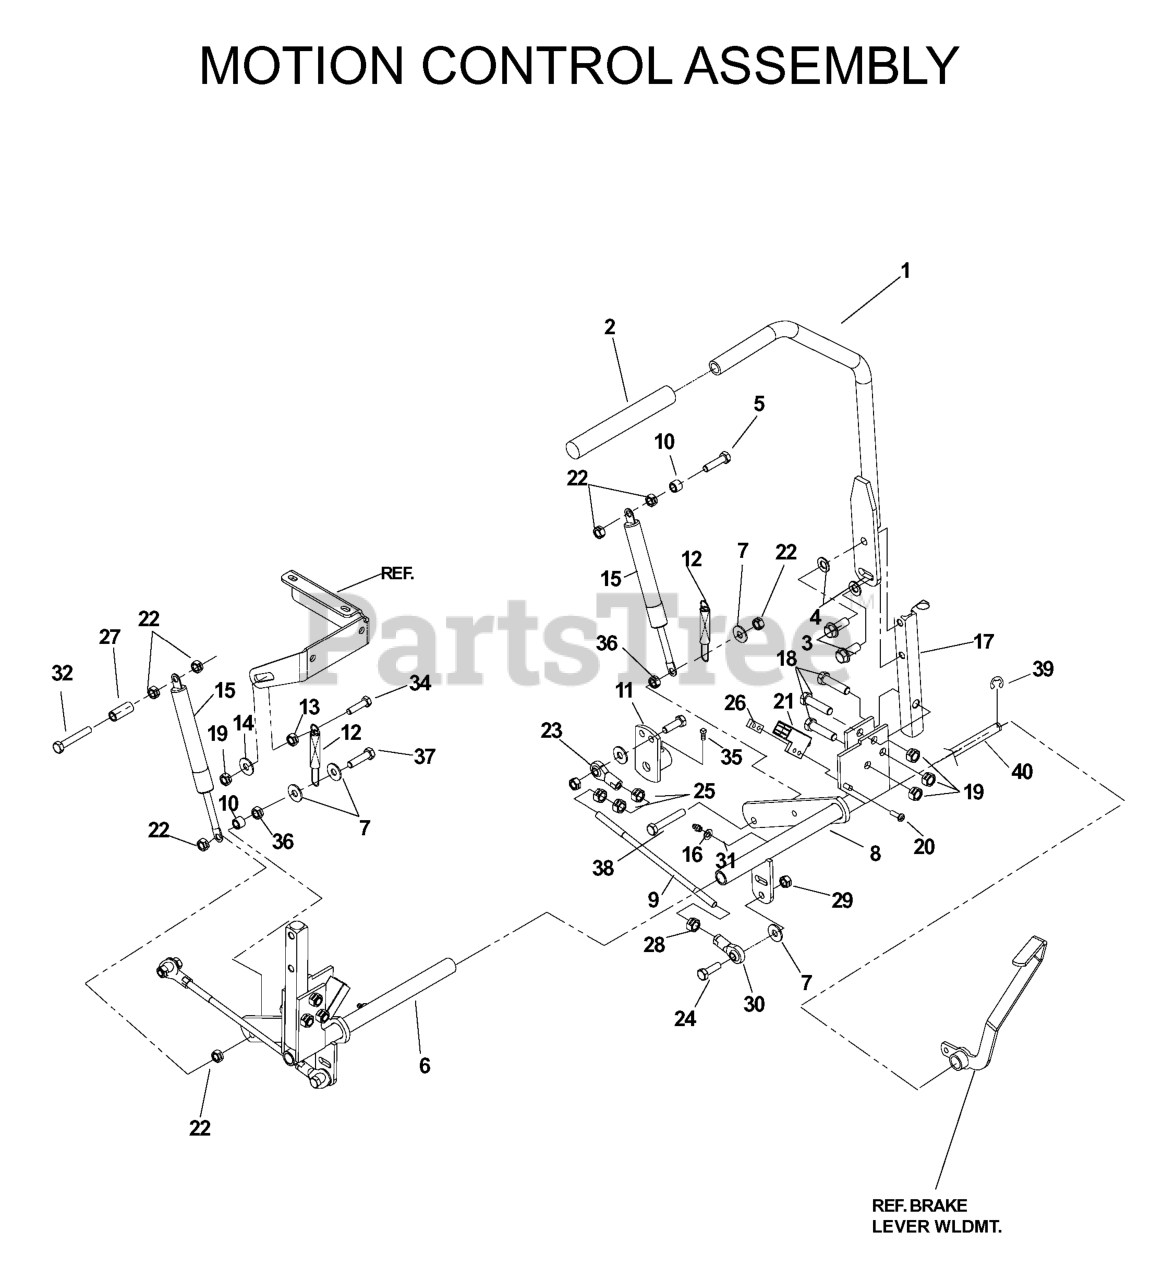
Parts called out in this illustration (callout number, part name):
1	CONTROL LEVER WELDMENT
3	HCS 3/8-16X1.GRD.5.ZD
4	WASHER, 3/8 DISC SPRING SPEC
5	CAPSCREW 5/16 X 1/1/2 HEX HEAD
6	CONTROL WLDMNT RH
7	WASHER 5/16 FLAT
8	CONTROL WLDMNT - LH
9	PUMP CONTROL LINK
11	PUMP LEVER
13	NUT 3/8C WHIZ
14	WASHER 3/8 FLAT
16	ZERK
17	CONTROL ARM
18	HCS 3/8-16 X 1 3/4 GR5
19	NUT 3/8-16 NYLOC
20	SCREW #10-24 X 5/8
21	SWITCH, INTERLOCK
22	NUT 5/16C CENTERLOCK
23	BALL JOINT, RIGHT HANDED
24	HCS 5/16C X 1 1/4
26	TAPPED PLATE
28	NUT 5/16F LEFTHAND
29	NUT 5/16 NYLOC
30	BALL JOINT, LEFT HANDED
32	HCS 5/16-18X2
33	HCS 3/8C X 3
34	HCS 3/8C X 2 1/2
35	5/16C X 5/8 "V" POINT
36	NUT 5/16C WHIZ
37	TAP BOLT 5/16C X 2 1/4
38	BOLT, TAP 5/16-18
39	E-RING 1/2 (2 2)
40	CONTROL SHAFT
